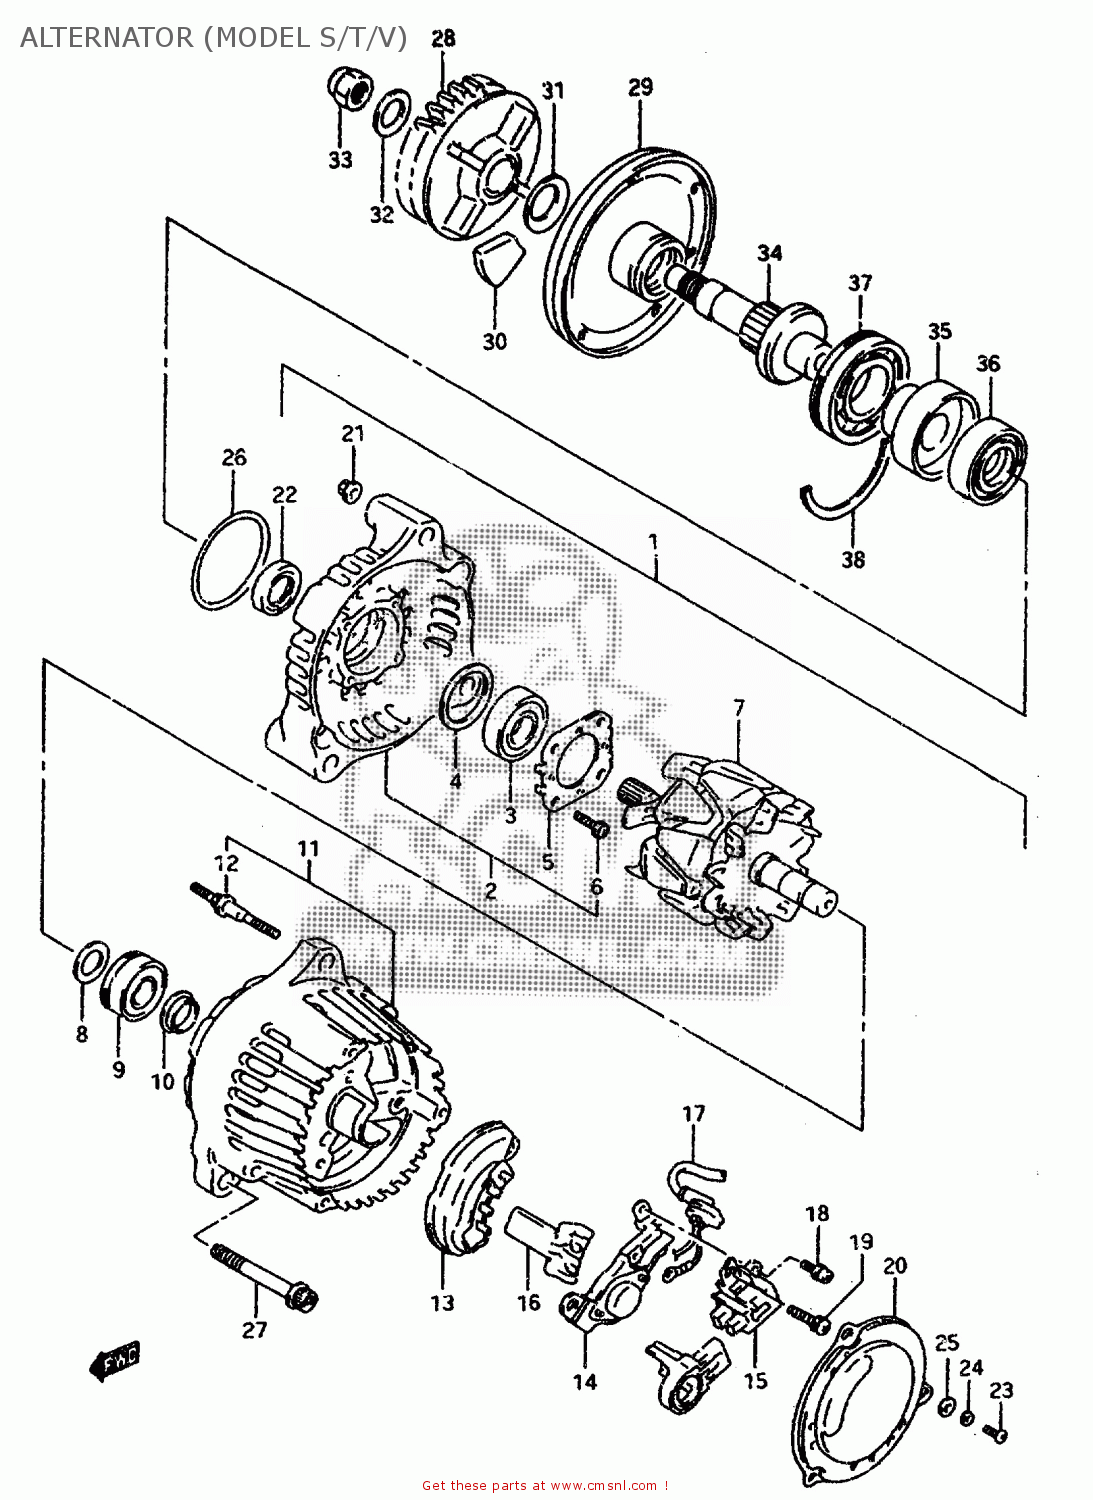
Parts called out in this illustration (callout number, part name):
1	ALTERNATOR ASSY
2	FRAME,DRIVE END
3	BEARING
4	COVER,BEARING
5	RETAINER,BEARING
6	SCREW,BEARING RETAINER
7	ROTOR ASSEMBLY
8	COVER,BEARING
9	BEARING
10	COVER(2)
11	FRAME,END
12	STUD BOLT
13	HOLDER,RECTIFIER
14	REGULATOR
15	HOLDER,BRUSH
16	COVER,RECTIFIER
17	WIRE,LEAD
18	SCREW 4X6
19	SCREW
20	COVER
21	NUT
22	SERVICE KIT(A)
23	SCREW
24	LOCK,WASHER
25	WASHER
26	O RING
27	BOLT
28	GEAR,GENERATOR DRIVEN
29	HOUSING,GENERATOR DAMPER
30	DAMPER,GENERATOR
31	WASHER
32	WASHER
33	NUT
34	SHAFT,GENERATOR DRIVE
35	HUB,GENERATOR DRIVE
36	COUPLING COMP,GENERATOR
37	C RING
38	C RING
